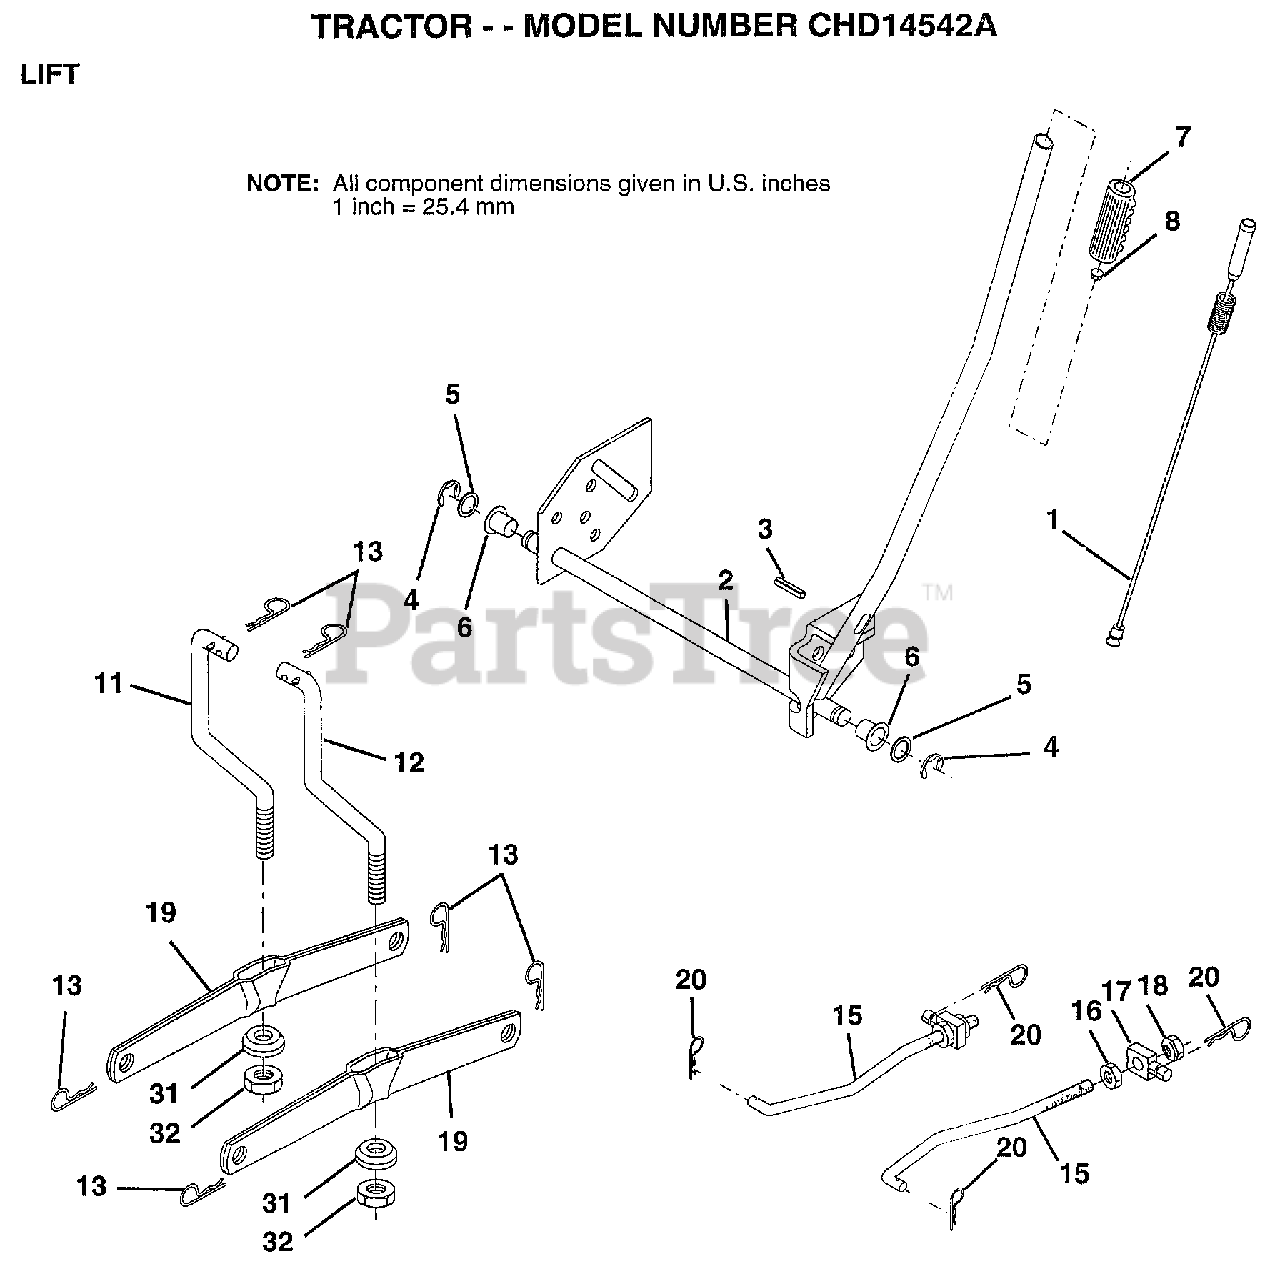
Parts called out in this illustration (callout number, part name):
1	WIRE ASM W.SPRING
2	"SHAFT ASM LIFT,RH"
3	PIN-GROOVE LT
5	WASHER
6	NYLON BEARING
7	GRIP
15	LINK.FRONT
16	NUT
17	TRUNION
18	NUT LTV
19	ARM SUSP REAR
20	RETAINER SPRING
31	BEARING PVT LH
32	NUT.CROWNLOCK.3/8
